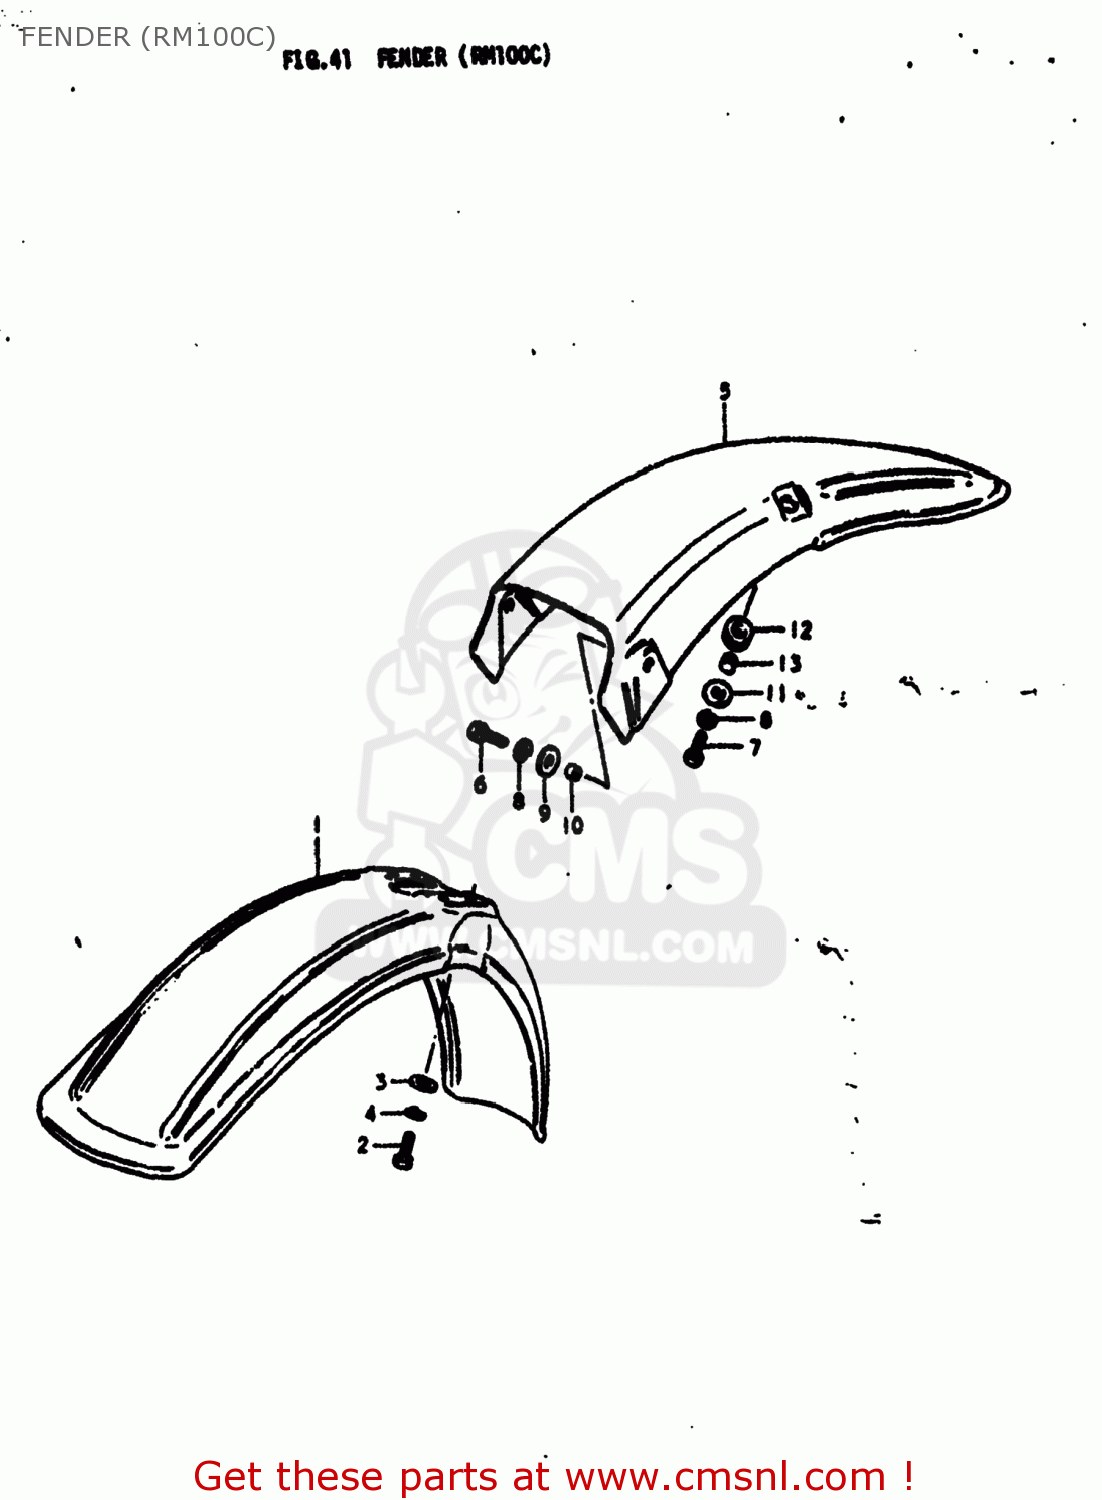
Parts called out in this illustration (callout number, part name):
1	FENDER,FRONT
2	BOLT, UPPER
3	WASHER
4	LOCK WASHER
5	FENDER,REAR
6	BOLT, UPPER
7	BOLT
8	LOCK WASHER
9	WASHER
10	SPACER (6.1X8X5.2)
11	WASHER (6.5X24X1.6)
12	CUSHION
13	SPACER
